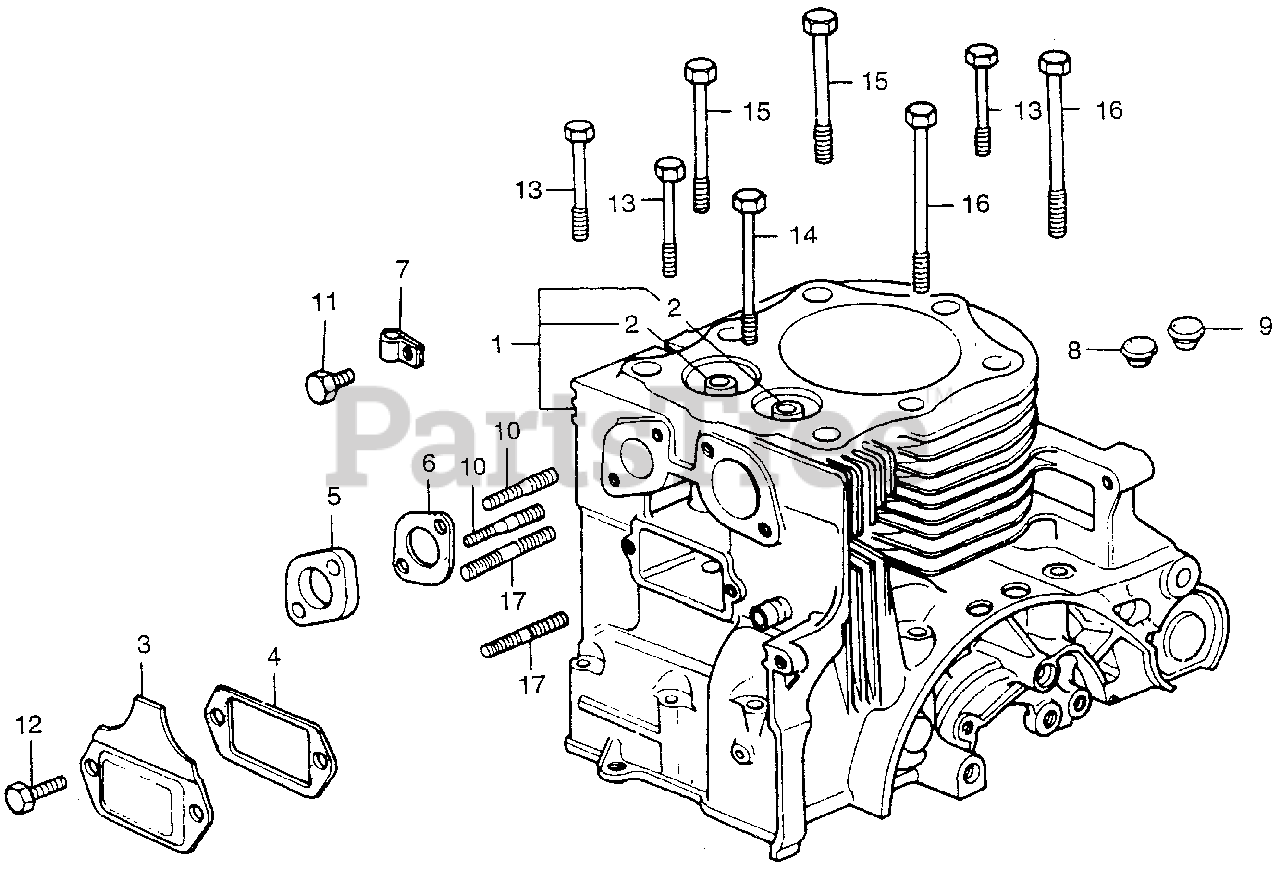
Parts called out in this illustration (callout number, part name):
2	GUIDE, VALVE
3	COVER, TAPPET
4	GASKET, TAPPET COVER (NOT AVAILABLE)
5	INSULATOR, CARBURETOR (NOT AVAILABLE)
6	GASKET, CARBURETOR INSULATOR
8	GROMMET, WIRE
9	GROMMET, WIRE
10	BOLT, STUD (8X39) (NOT AVAILABLE)
12	BOLT, HEX. (6X12)
13	BOLT, HEX. (6X63)
14	BOLT, HEX. (6X90)
15	BOLT, HEX. (8X80) (SOURCE: VINTAGE PARTS INC.)
16	BOLT, HEX. (8X100)
17	BOLT 2, STUD (6X20)
